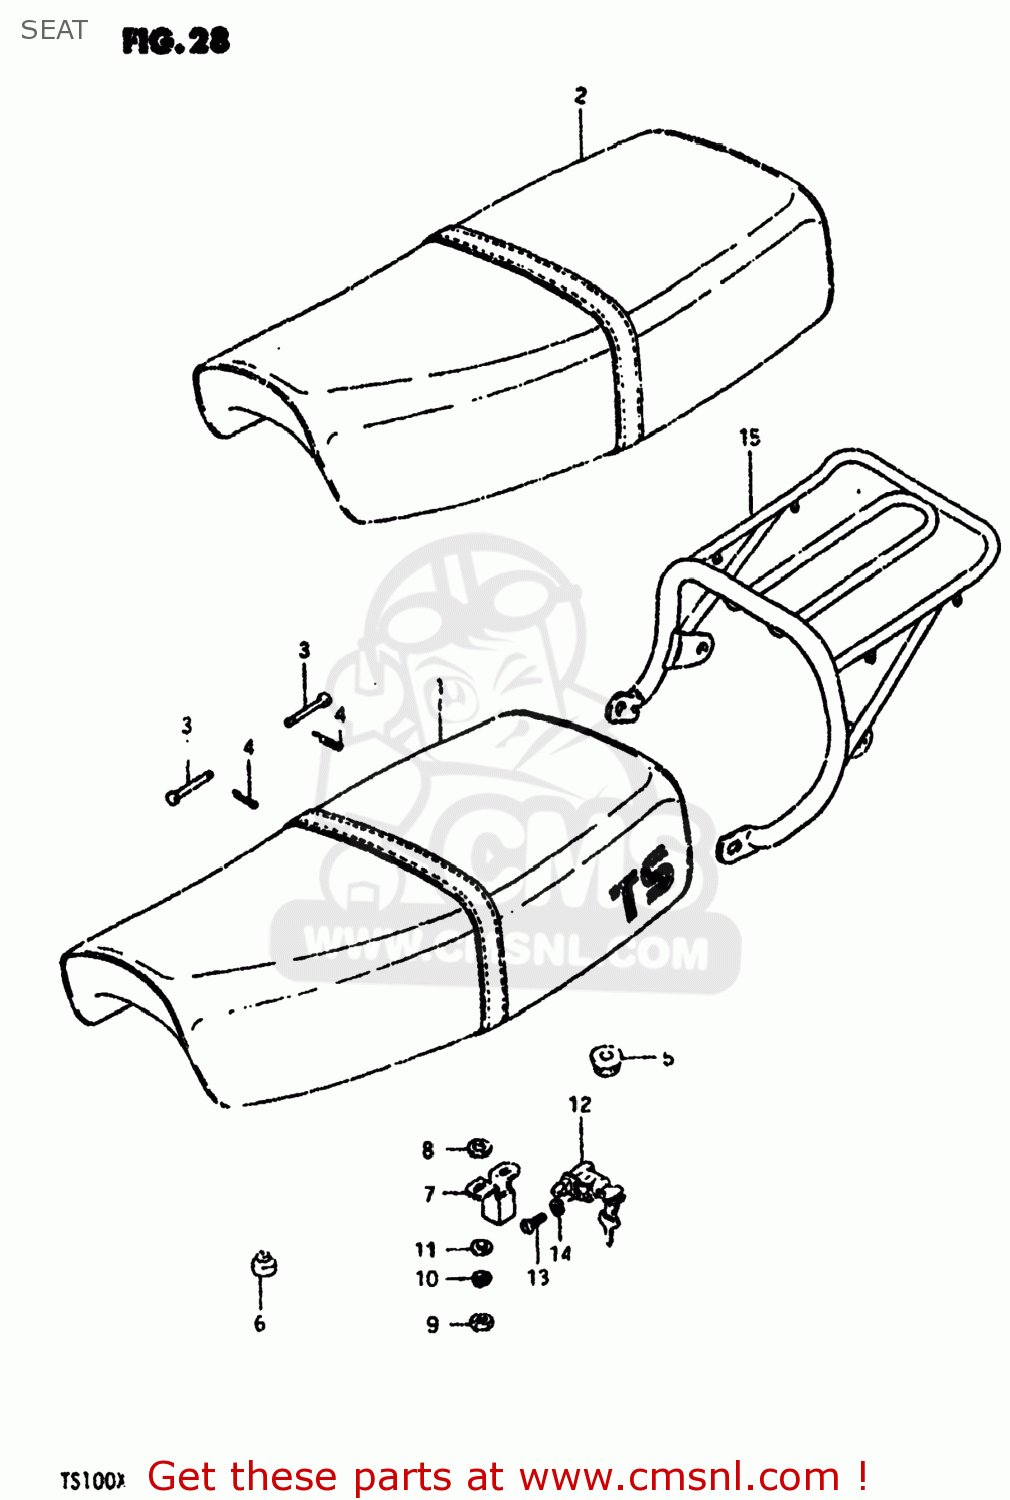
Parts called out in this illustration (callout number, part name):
1	SEAT ASSEMBLY
2	SEAT ASSEMBLY
3	PIN
4	PIN
5	CUSHION
6	CUSHION
7	PLATE,CLAMP GUIDE
8	WASHER(8.5X18X1)
9	NUT
10	LOCK WASHER
11	WASHER
12	LOCK ASSY,SEAT
13	SCREW
14	LOCK WASHER
15	CARRIER,SPORT
